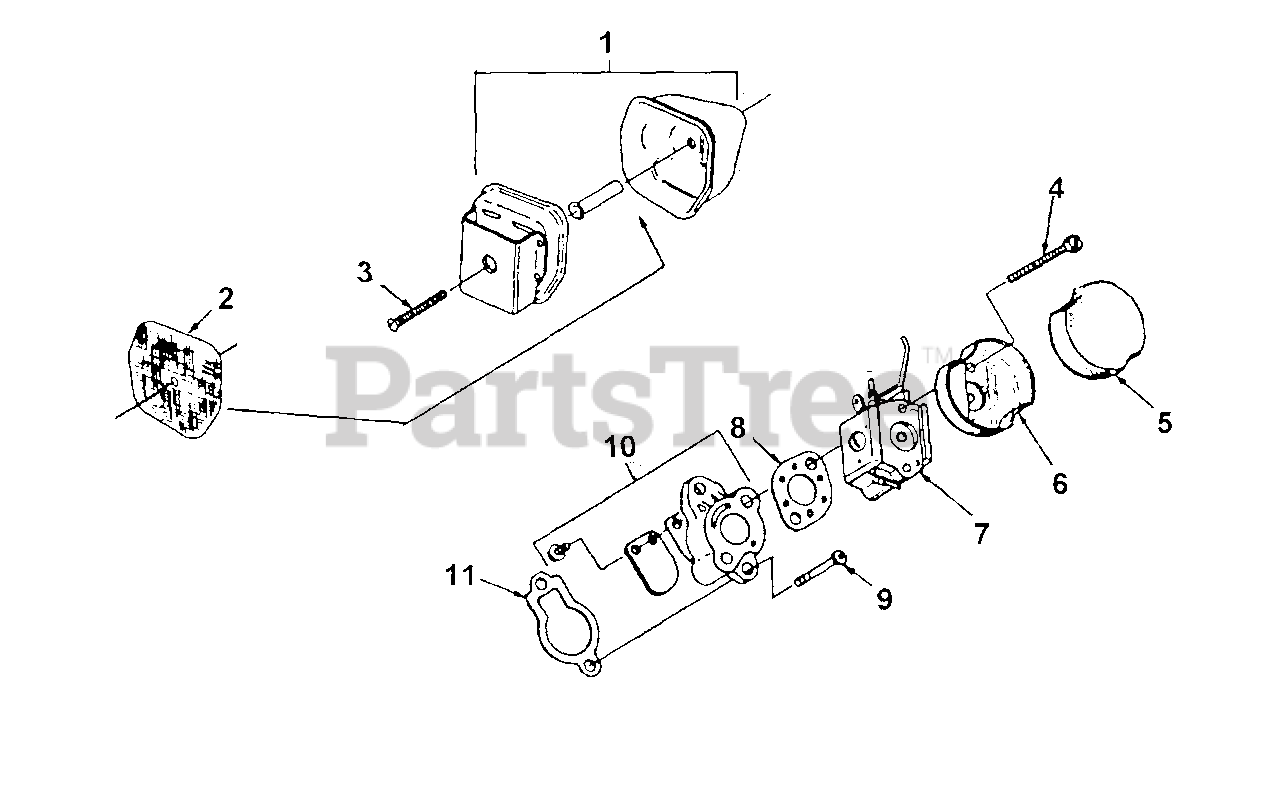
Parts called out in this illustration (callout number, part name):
1	MUFFLER ASSY.
2	SCREEN, SPARK ARRESTOR
3	SCREW, SEMS (10-24 x 1 7/8")
4	SCREW, SELF TAPPING (#8 x 1.65")
5	FILTER, AIR
6	CUP, FILTER
7	CARBURETOR ASSY.
8	GASKET, CARBURETOR
9	SCREW, SELF TAPPING (10-24 x 7/8")
10	HEAT DAM & REED
11	GASKET, HEAT DAM
